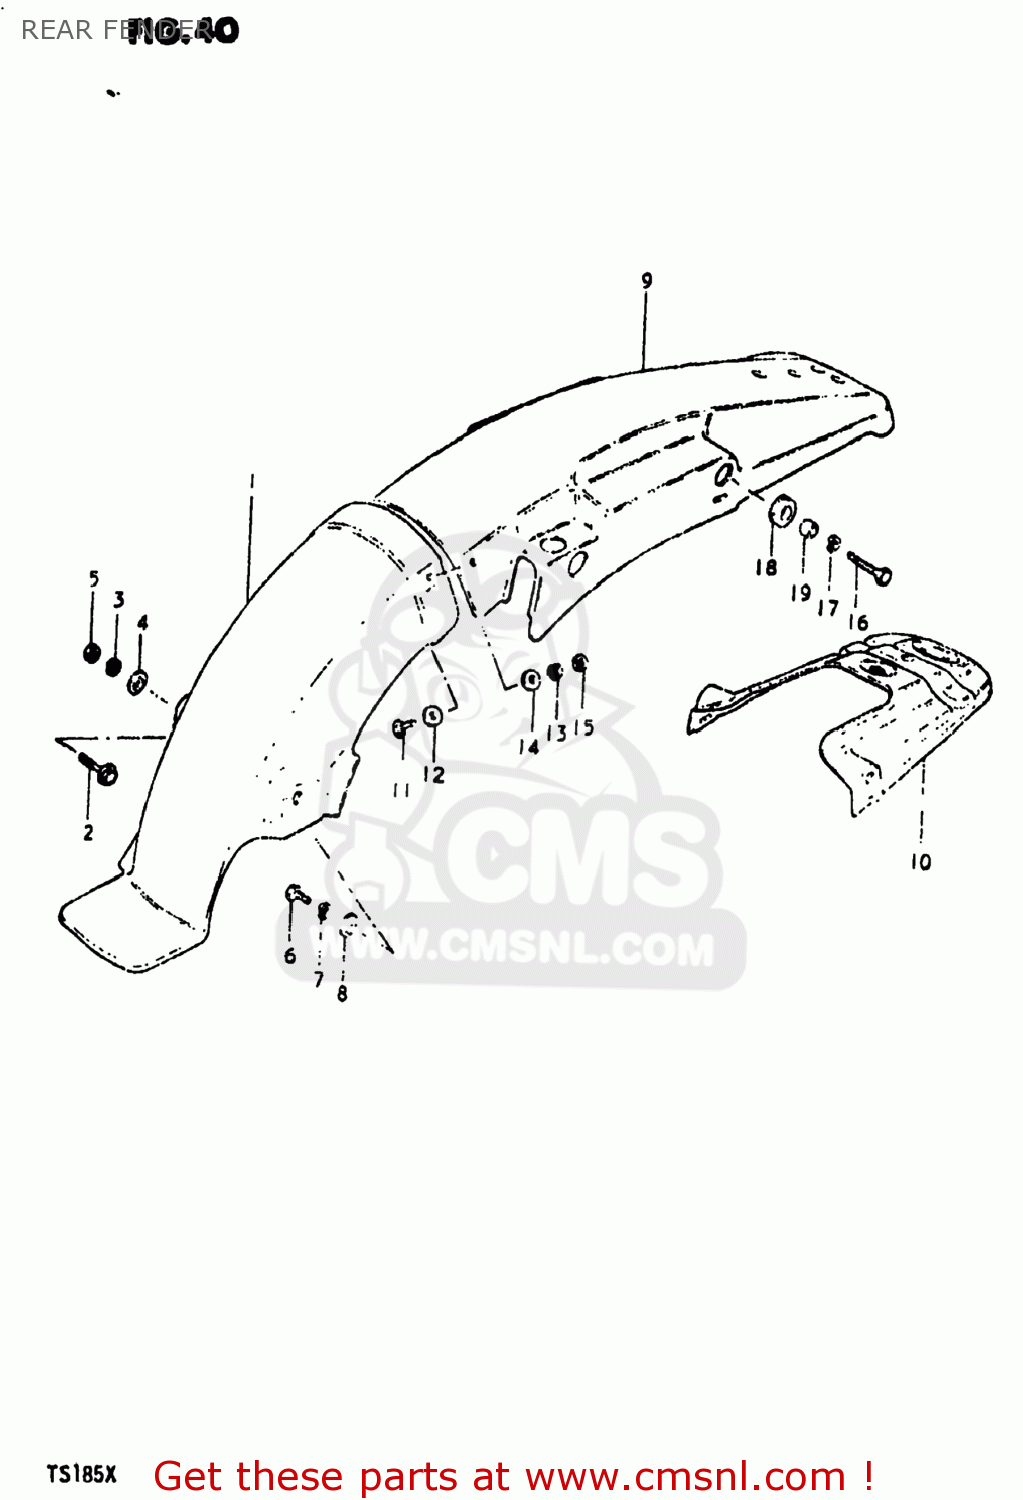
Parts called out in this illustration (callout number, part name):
1	FENDER,REAR
2	BOLT
3	LOCK WASHER
4	WASHER
5	NUT
6	BOLT
7	LOCK WASHER
8	WASHER
9	BODY,REAR FENDER,REAR
10	REINFORCEMENT,RR FENDER
11	BOLT
12	WASHER (5.5X16X1.2)
13	LOCK WASHER
14	WASHER(5.2X16X1)
15	NUT
16	BOLT (8X30)
17	LOCK WASHER
18	CUSHION
19	SPACER (8.2X12X7.5)
